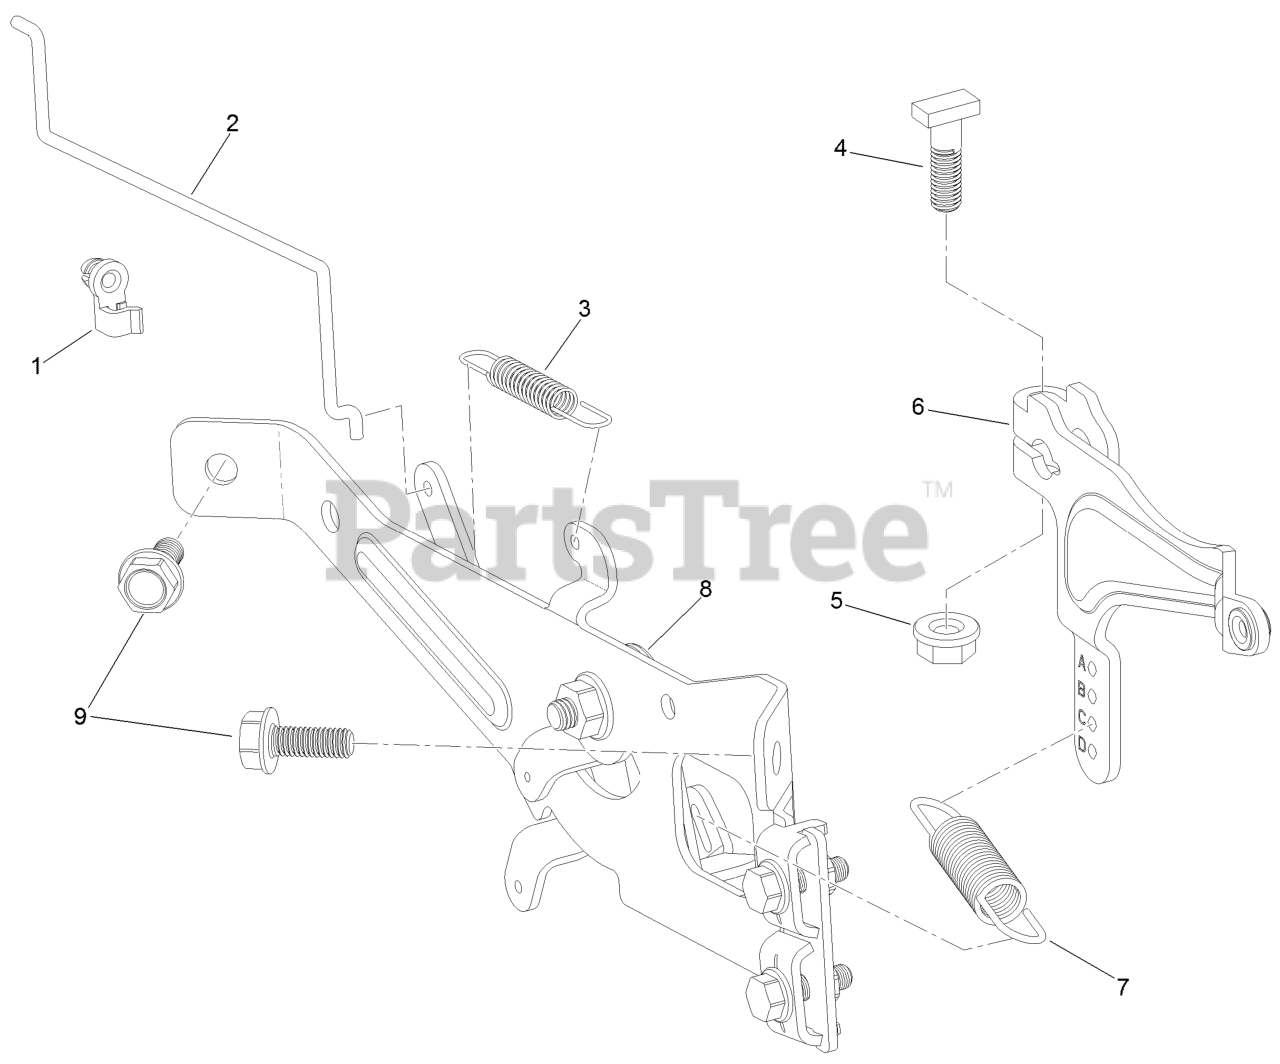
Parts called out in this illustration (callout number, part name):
1	CLIP-LINKAGE
2	LINKAGE-CHOKE
3	SPRING-GOVERNOR
4	BOLT-ARM, GOVERNOR
5	NUT-FLANGE
6	ARM-GOVERNOR
7	SPRING-GOVERNOR
8	PLATE-CONTROL
9	SCREW-HHF
